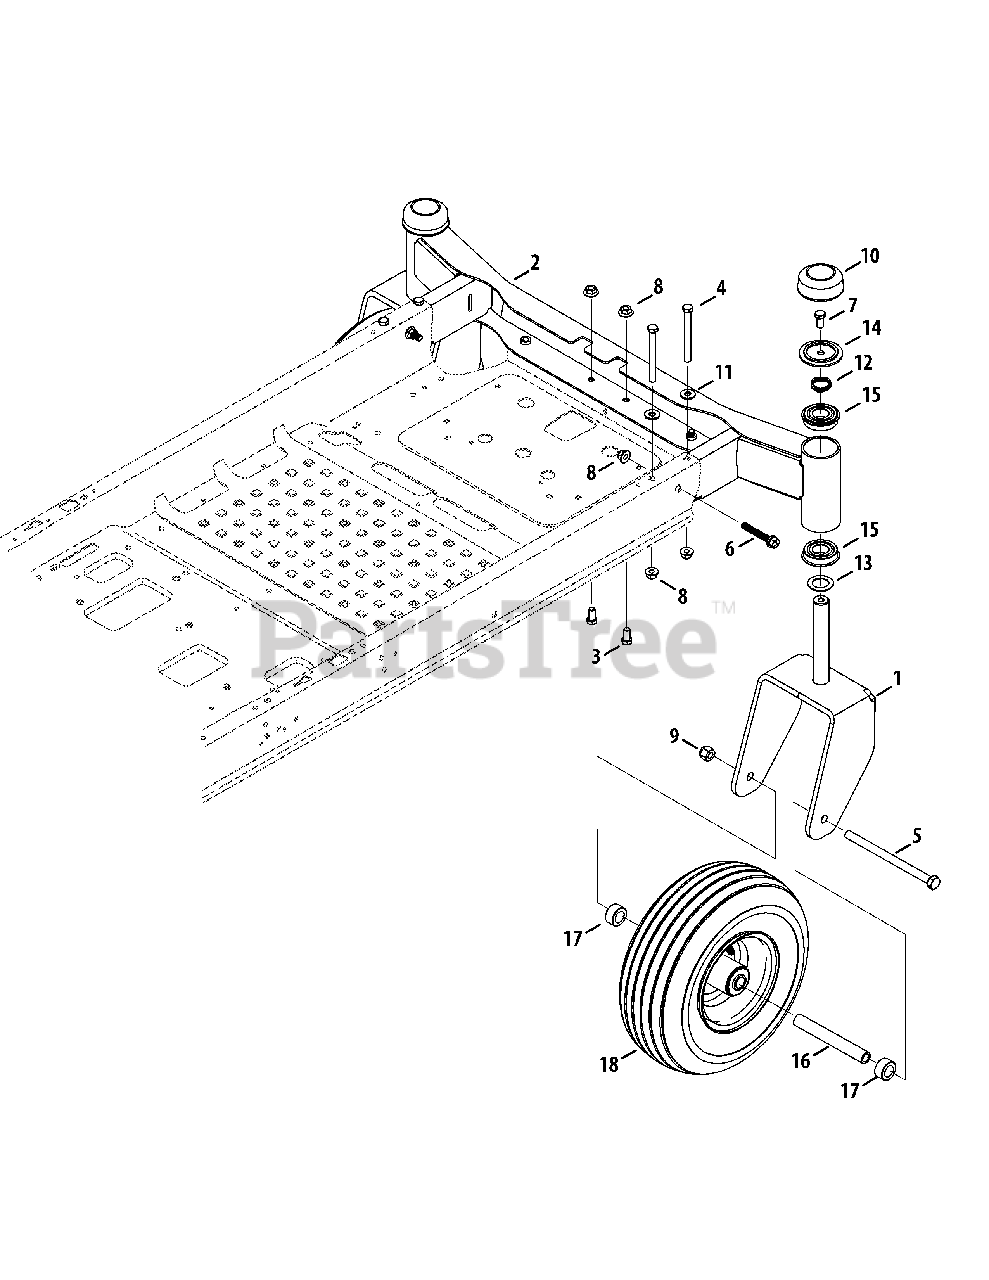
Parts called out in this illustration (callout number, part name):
1	Caster Wheel Bracket
3	Hex Cap Screw, 3/8-16 x .75
4	Hex Cap Screw, 3/8-16 x 3.75
5	Hex Cap Screw, 1/2-20 x 7.25
6	Hex Flange Screw, 3/8-16 x 2.00
7	Hex Cap Screw, 3/8-16 x .750
8	Flange Lock Nut, 3/8-16
9	Hex Lock Nut, 1/2-20
11	Flat Washer, .385 x .870 x .092
12	Wave Washer, 1.25 x 1.00 x .300
13	Flat Washer, 1.010 x 1.56 x .060
14	Shoulder Spacer, 2.50 x .200
15	Ball Bearing
16	Spacer, .51 x .75 x 5.825
17	Spacer, .76 x 1.23 x .63
